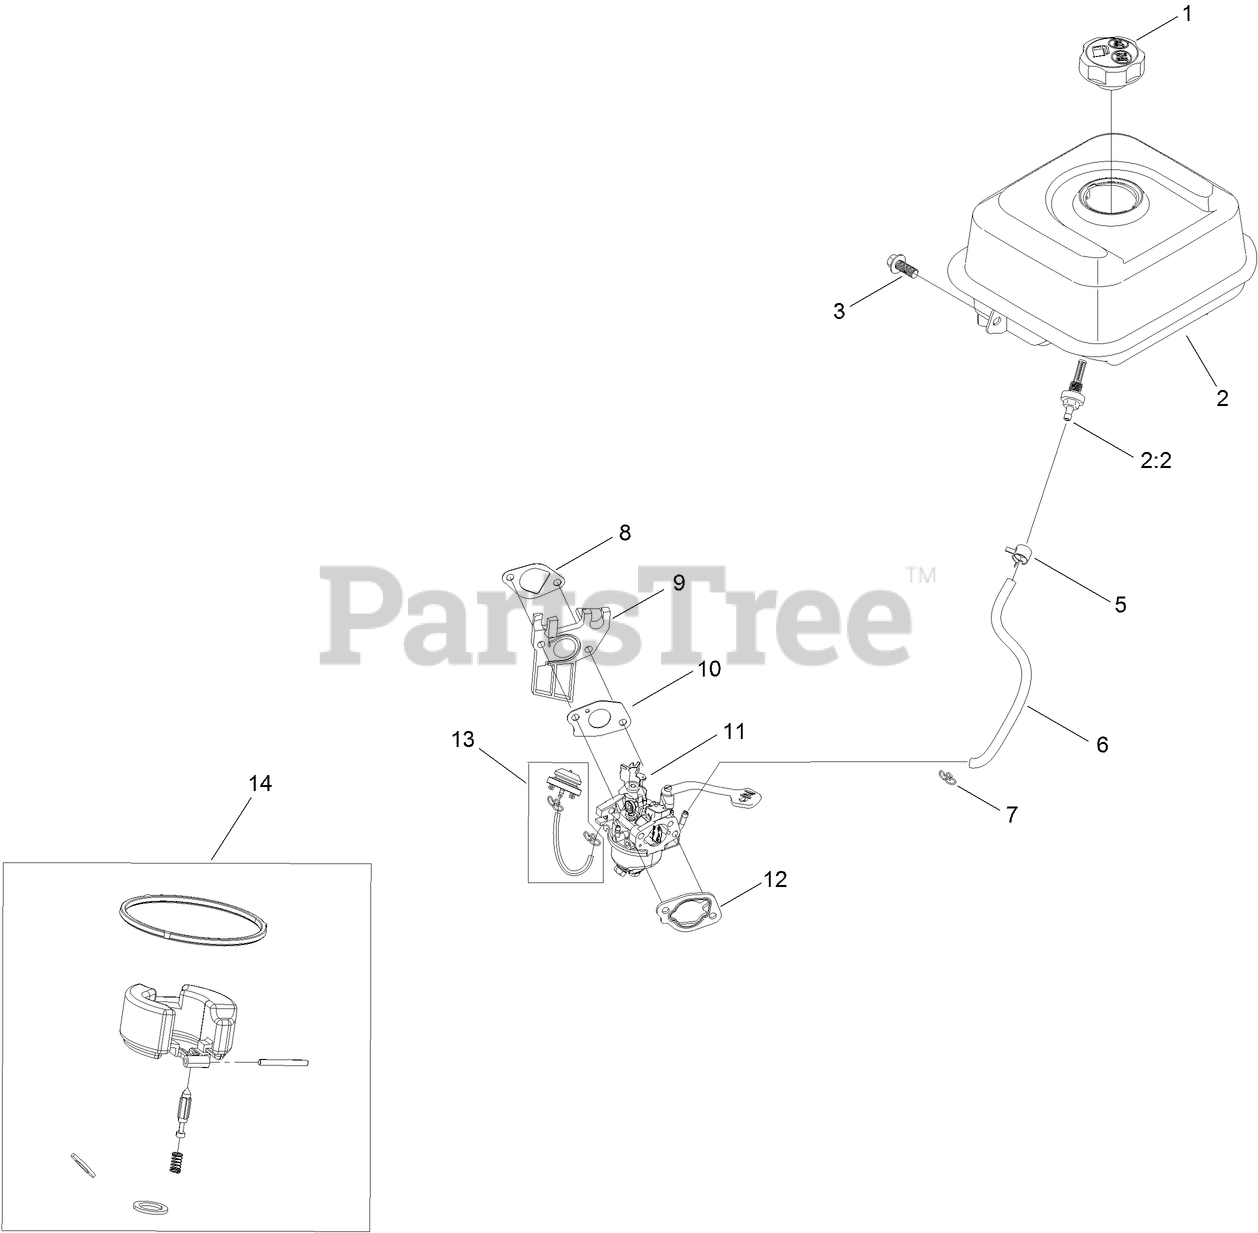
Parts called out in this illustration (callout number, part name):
2	FUEL TANK AND FILTER ASM
2:2	FILTER-FUEL
3	SCREW-HHF
5	CLAMP-HOSE
6	HOSE-FUEL
7	CLAMP-HOSE
8	GASKET-CARBURETOR
9	INSULATOR-CARBURETOR
10	GASKET-CARBURETOR
11	CARBURETOR ASM
12	GASKET-CARBURETOR
13	PRIMER KIT
14	INTERNAL CARB SERVICE KIT
